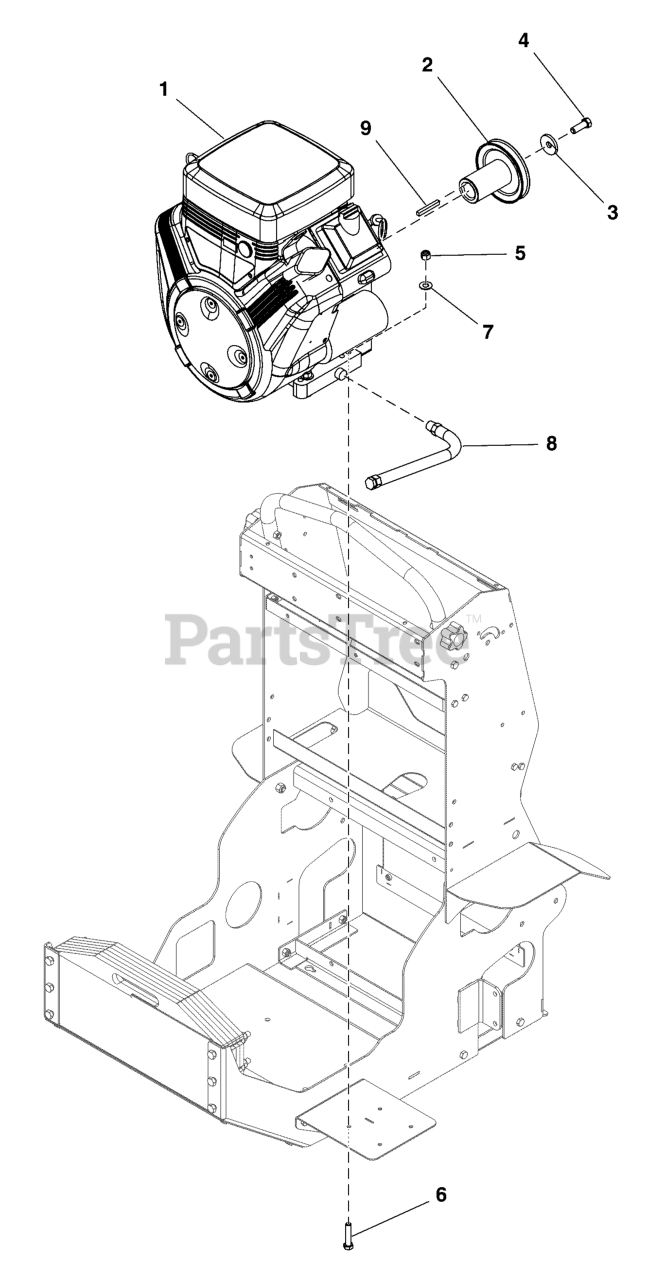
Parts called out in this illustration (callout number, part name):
1	ENGINE, 18 HP VANGUARD
2	PULLEY, 4.50 O.D. x 1.125" I.D. V, A/B
3	WSHR-STL, BLV, .450" X 1.500" X .172" MZ
4	SCR-CAP, HEX .4375"-20 X 1.250" EP42 G8 YZ
5	NUT-HEX-NYLK, .375"-16 SS188
6	SCR-CAP, HEX .375"-16 X 1.7500" SS188
7	WSHR-STL, FLT .406" X .875" X .050" IS SS188
8	HOSE, OIL DRAIN
9	KEY, .250" SQ. X 2" SS188
